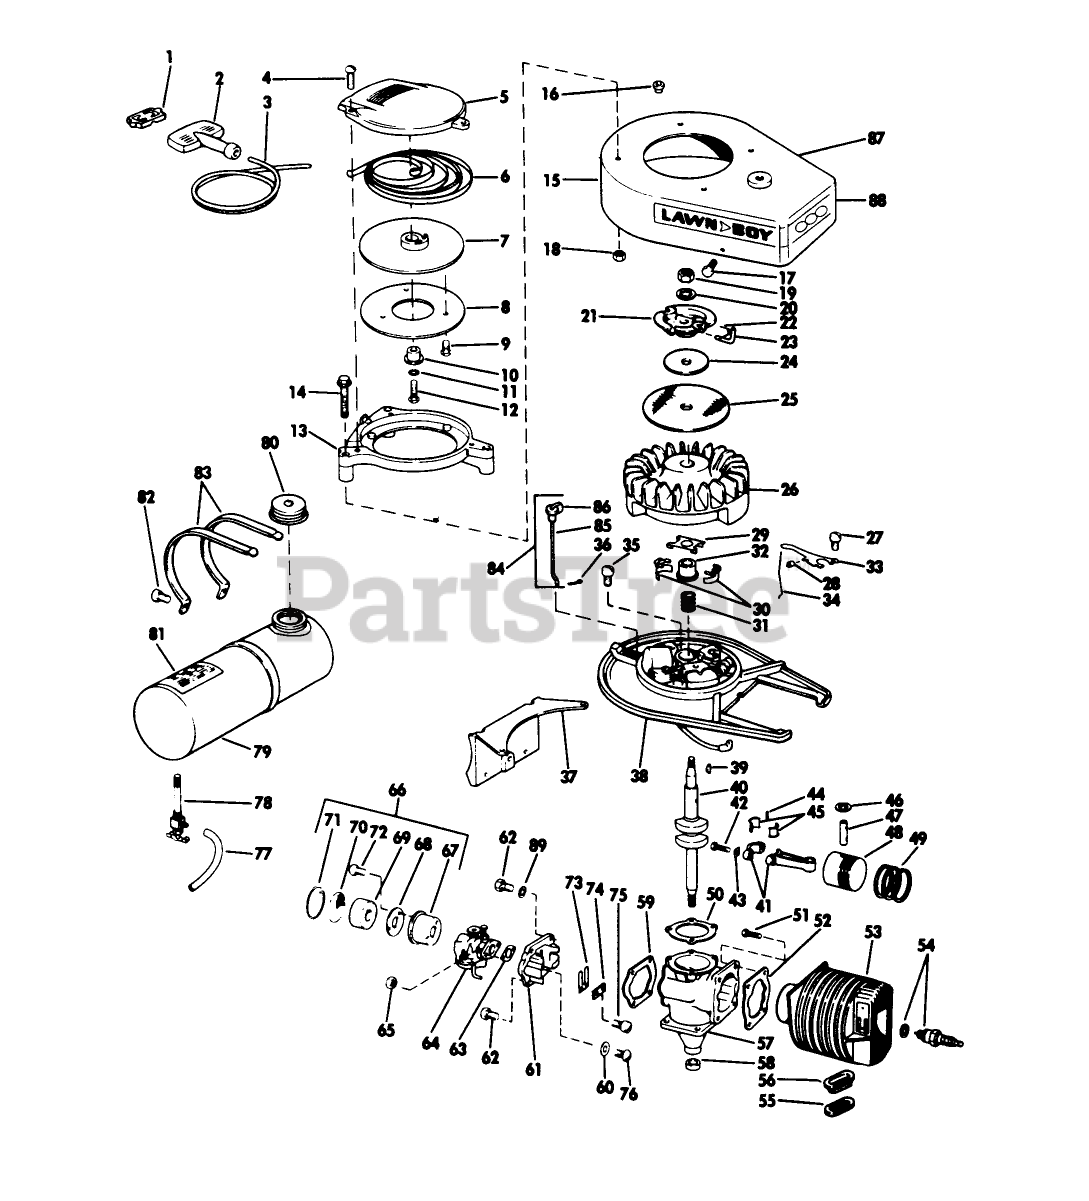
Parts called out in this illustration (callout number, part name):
6	RECOIL SPRING
17	SCREW S
23	PIN - STARTER
28	WEAR BLOCK S
29	COLLAR S
33	GOVERNER LEVER AY
34	GOVERNOR ROD S
35	SCREW S
36	Cotter Pin
45	LINER ASM
46	RING-RETAINING
50	GASKET S
52	GASKET S
55	GASKET S
62	SCREW S
63	GASKET S
65	STOP NUT
68	BACK-UP PLATE
69	ELEMENT
74	PLATE-BACKUP, REED
76	Screw-Reed Plate to Carb.
78	VALVE&SCREEN SM
